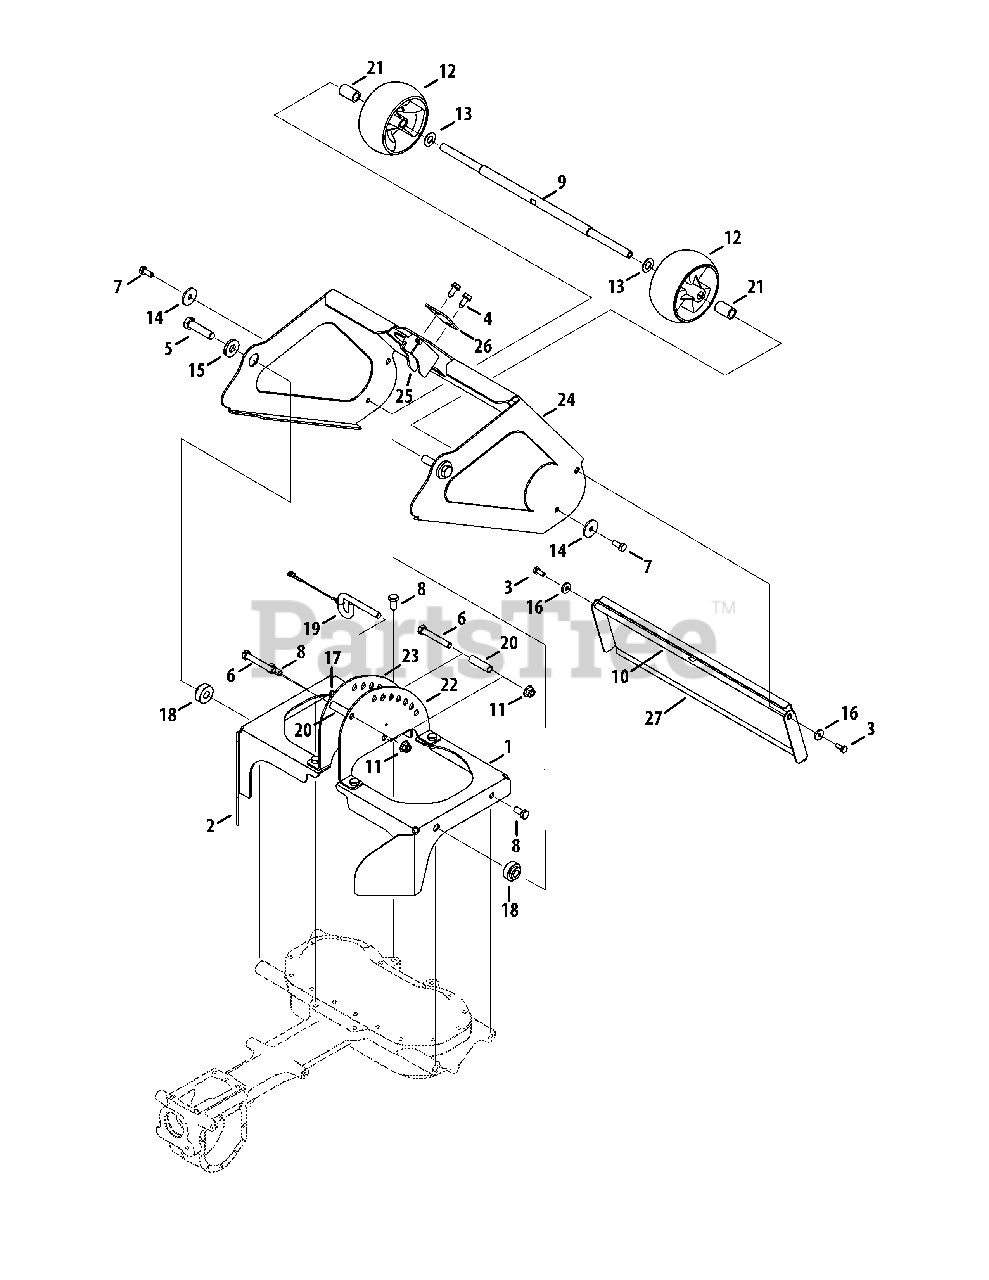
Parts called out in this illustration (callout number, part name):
1	Tine Shield Assembly, LH
2	Tine Shield Assembly, RH
3	Hex Screw, 1/4-20 x .625
4	Hex Washer Screw, 5/16-18 x .750
5	Hex Screw, 1/2-13 x 2.00
6	Hex Screw, 3/8-16 x 2.50
7	Hex Head Screw, 5/16-18 x .75, Patch
8	Hex Screw, 3/8-16 x .75
9	Wheel Shaft
10	Rear Tine Shield Rod
10	Washer .405 x .985 x .042
11	Flangelock Nut, 3/8-16
12	Deck Ball Wheel, 5.0
13	Washer, Flat, .510 x 1.00 x .060
14	Washer, Flat, .330 x 1.25 x .120
15	Flat Washer, .531 x 1.25 x .181
16	Washer, Flat, .250 x .750 x .119
17	Shoulder Screw, #10-32 x .500
18	Shoulder Spacer, .510 x .890 x .190
19	Lock Rod, .375
20	Spacer, .386 x .63 x 1.75
21	Spacer, .525 x .775 x 1.245
22	Height Adjustment Bracket, LH
23	Height Adjustment Bracket, RH
24	Tine Pivot Shield
25	Tine Shield Stop Bracket
26	Shield Stop Mounting Plate
27	Rear Tine Shield
